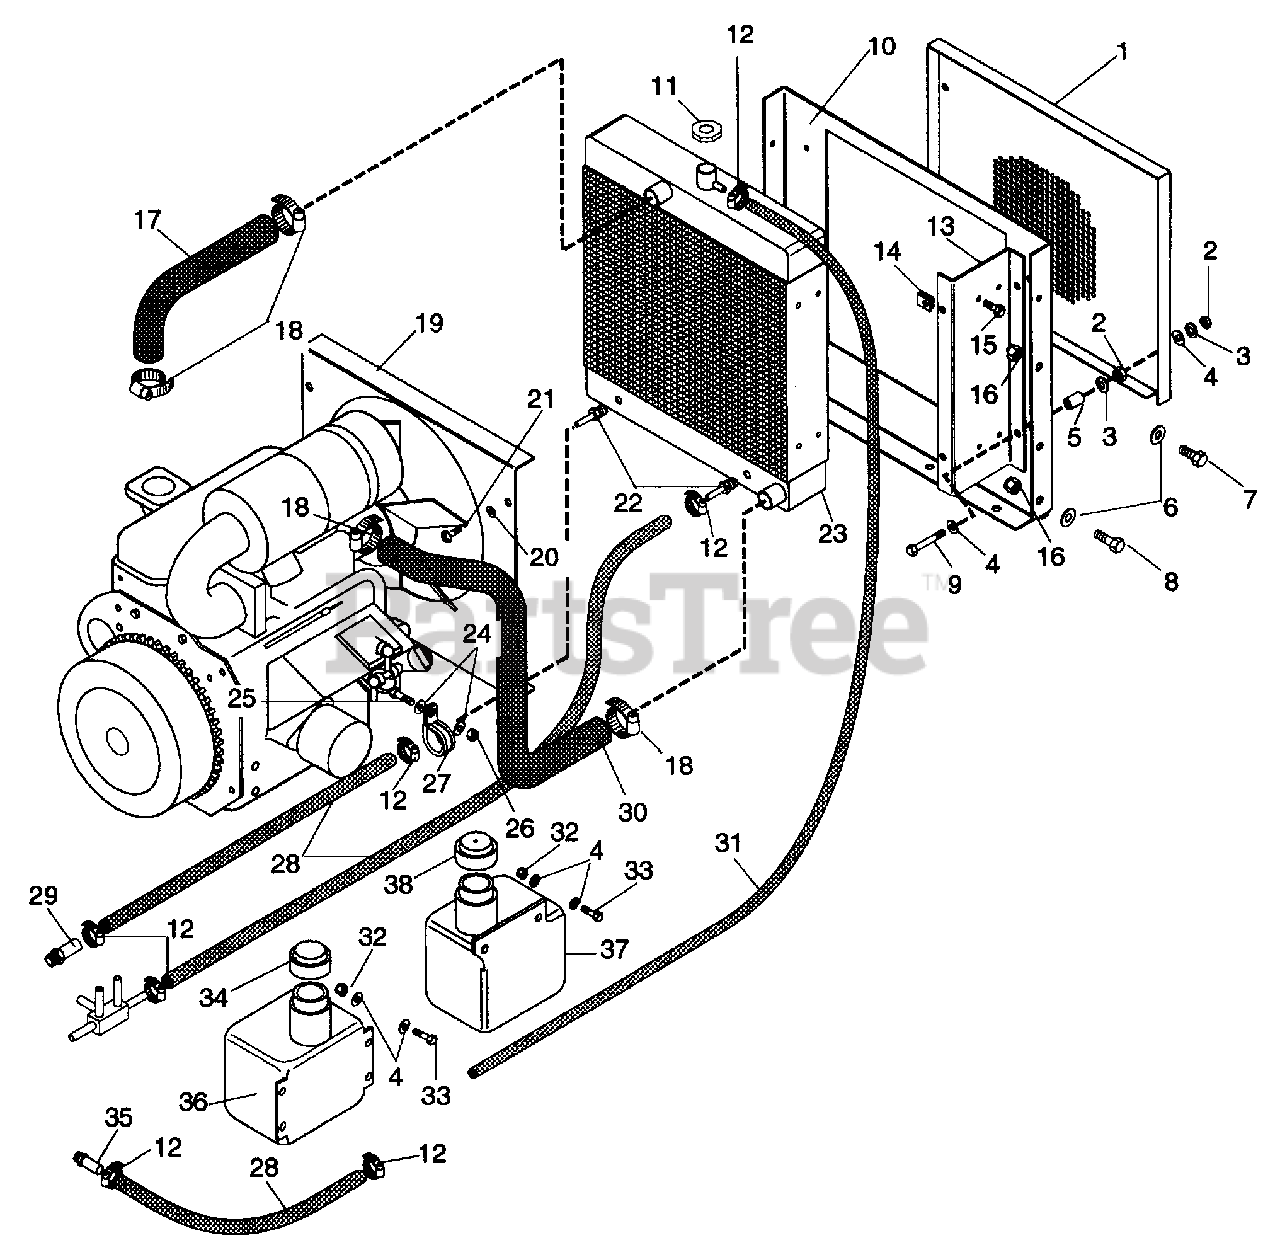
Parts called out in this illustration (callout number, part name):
1	CVR, AIR
2	NUT-HEX .312-18
3	WSHR-LOCK .313 X .078 PL
4	WSHR-FL-STL .344 X .688 X .065
5	BSHG-SLV .407 X .625 X .750 PL
6	WSHR-FL-STL .531 X 1.062 X .095
7	BLT-HEX .50-13 X 1 PL GR 5
8	BLT-HEX .50-13 X 1.50 PL GR 5
9	BLT-HEX .31-18 X 2.00 PL GR 5
10	MOUNT, RADIATOR
11	CAP, RADIATOR
12	HOSE CLAMP
13	BRKT, RADIATOR
14	NUT-RTNR .25-20 X .56
15	BLT-HEX .31-18 X .50
16	NUT-LK-NYL .50-13 PL
17	HOSE, UPPER RADIATOR
18	CLAMP-HOSE 1.50 X .81 X 1.42
19	CVR, FAN
20	WSHR-FL-STL .281 X .625 X .065
21	SCR-MCH .25-20 PAN HD
22	ADPTR .38 MA PIPE TO .38 TUBE
23	RADIATOR, FLAT PLATE
24	WSHR-FL-STL .406 X .812 X .065 PL
25	BLT-HEX .38-16 X 1.00 PL GR 5
26	NUT-LK-NYL .375-16 PL
27	CLAMP, CUSHIONED STEEL
28	HOSE, HYDRAULIC
29	FTG-ADPTR .562-18 ST THD
30	HOSE, LOWER RADIATOR
31	HOSE, 5/16 LD
32	NUT-LK 10-24 NY PL
33	BLT-HEX .44-20 X .75 GR 5
34	CAP, 2" VENTED
35	CONN, HOSE
36	TANK, PLASTIC 2.0 QT
37	TANK, PLASTIC 1.5 QT
38	CAP, 1-5/8 VENTED
NS	G-DECAL, DANGER HAND
